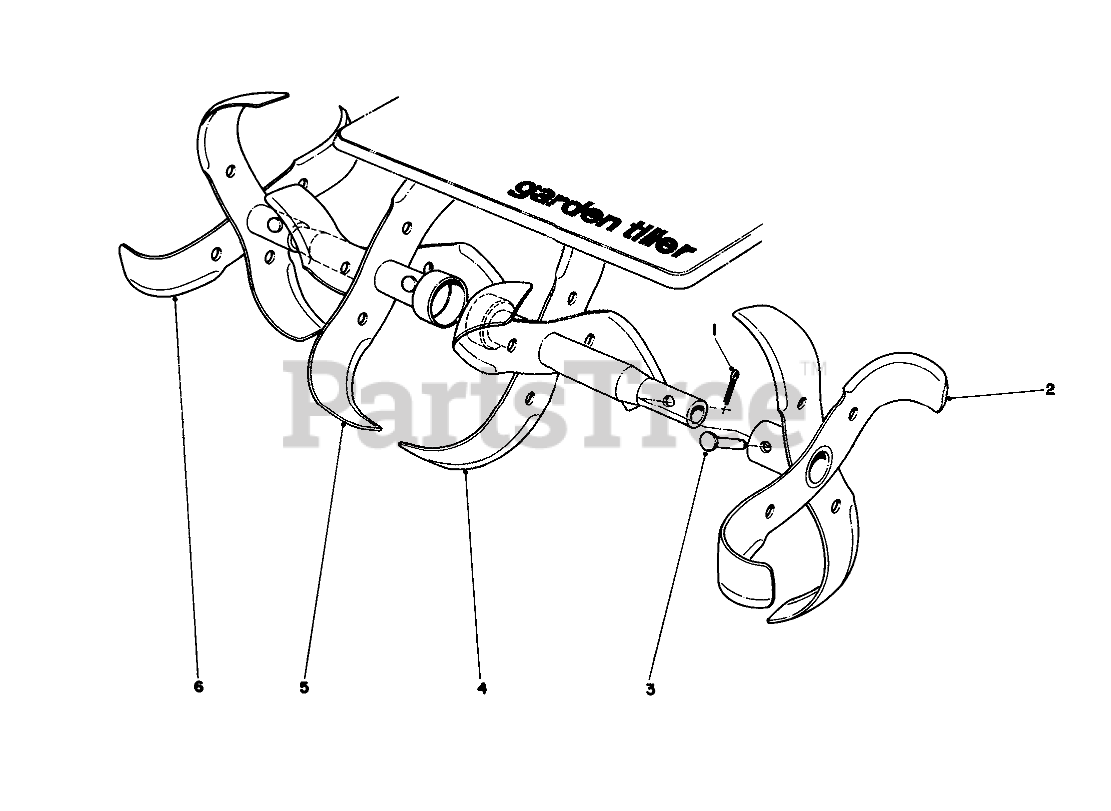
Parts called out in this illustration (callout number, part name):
1	PIN-COTTER
2	LH OUT SLASH TINE WA
3	TINE PIN
4	Inner Tine L.H.
5	Inner Tine R.H.
6	RH OUT SLASH TINE EA
